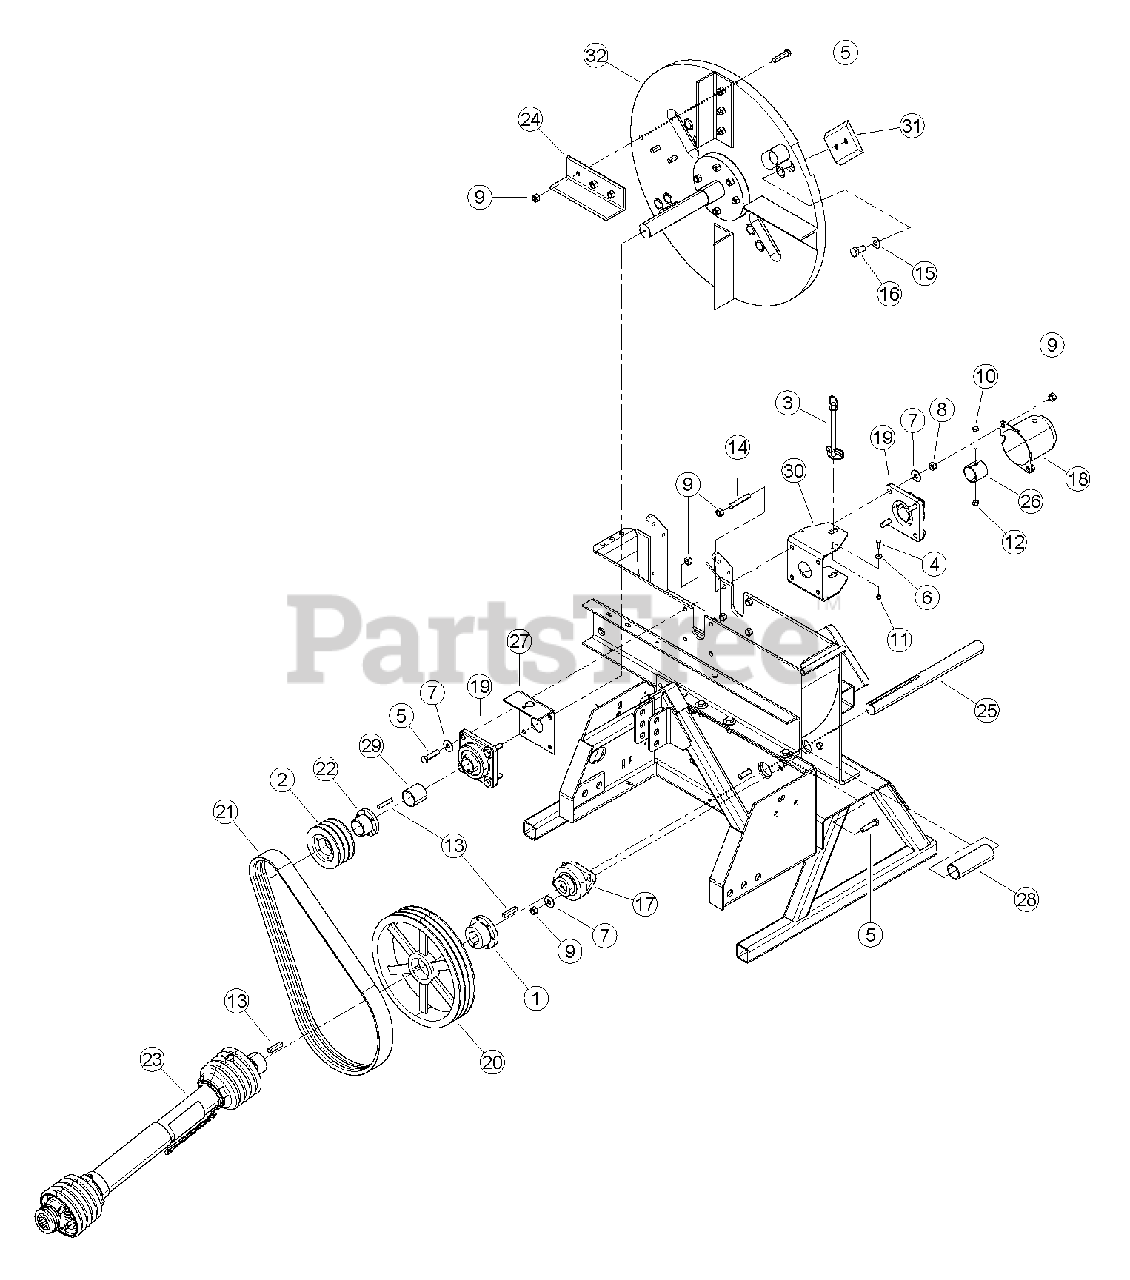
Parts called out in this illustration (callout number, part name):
1	BUSHING, SK 1-1/2
2	SHEAVE 3B4.8 SD
3	PIN, HITCH 1/2 X 6-1/2 W LYNCH
4	BOLT, 1/4 X 3/4 HEX HD GR5 ZP
5	BOLT, 1/2 X 2 HEX HD GR5 ZP
6	WASHER, 1/4 FLAT ZP
7	WASHER, 1/2 FLAT ZP
8	NUT, 1/2 HEX NC ZP
9	NUT, 1/2 CENTERLOCK GRB ZP
10	BOLT, 3/8 X 2-1/2 HEX HD GR5 ZP
11	NUT, 1/4 NE NYLOCK ZP
12	NUT, 3/8 NE NYLOCK ZP
13	KEY, 3/8 SQUARE X 2 LONG PLAIN
14	STUD, 1/2-13 X 3 LONG B7 ZP
15	WASHER, 5/8 SAE HARDENED
16	BOLT, M16 X 2.0 X 30 HEX HD W/PATCH
17	BEARING, 2 BOLT FLANGE 1-1/2 BORE
18	CAP, LARGE SHAFT
19	BEARING, 4 BOLT FLANGE 1-3/4 BORE
20	SHEAVE, 3B13.6 SK
21	BELT, 3RB64
22	BUSHING, SD 1-3/4
23	DRIVELINE, 33.9/47.6 1-1/2 RND/1-3/8 6 SPL
24	PADDLE, BIG CHIPPER
25	JACKSHAFT, CHIPPER DRIVE
26	COLLAR, CHIPPER LOCK
27	WELDMENT, LEFT BEARING BRACKET
28	SHIELD, SHAFT
29	SPACER, 2.0 X 1.88
30	BRACKET, ROTOR LOCK
31	BLADE, BIG CHIPPER
32	ASSEMBLY, 9 INCH CHIPPER ROTOR
